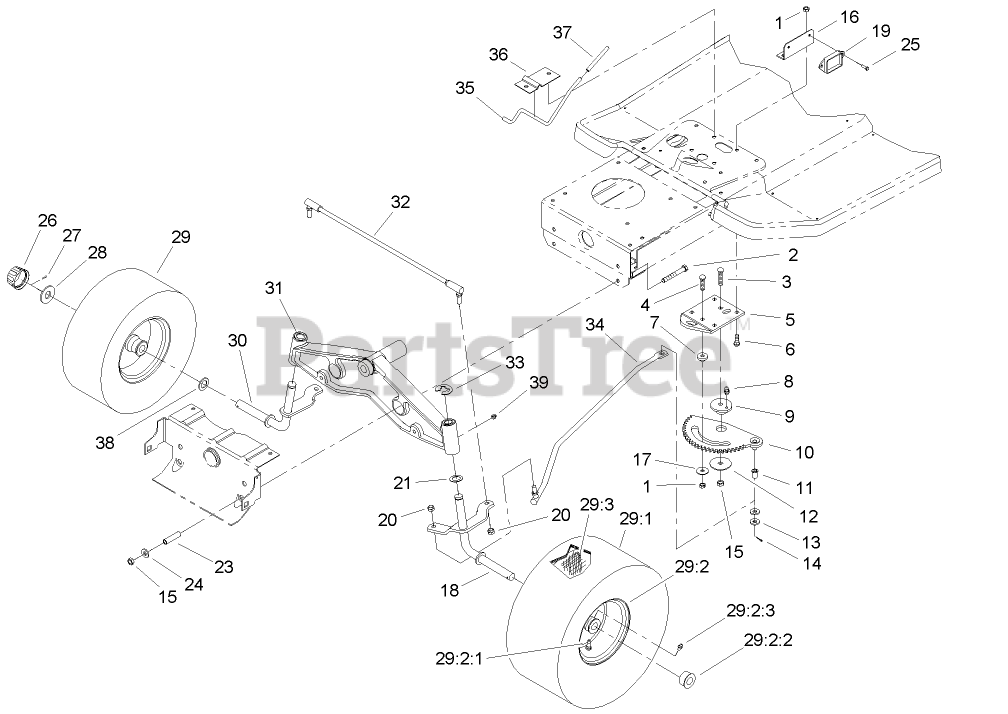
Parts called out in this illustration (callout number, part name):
1	NUT-LOCK, NI
2	SCREW-HH
3	SCREW-CARR
4	SCREW-CARR
5	BRACKET-RACK, STEERING
6	BOLT-CARR
7	SPACER-RACK, STEERING
8	FITTING-GREASE
9	BUSHING-ECCENTRIC
10	RACK-STEERING
11	BUSHING-FLANGED, NYLON
12	WASHER-BEARING
13	WASHER-FLAT
14	PIN-COTTER
15	NUT-LOCK, NI
16	BRACKET-MODULE
17	WASHER-PIVOT
18	LH SPINDLE ASM (BLACK)
19	MODULE
20	NUT-HEX
21	WASHER-THRUST
23	SPACER
24	WASHER-FLAT
25	SCREW-HWH
26	CAP-HUB
27	PIN-COTTER
28	WASHER-PLAIN
29	Loose Parts Package
29:2:2	BEARING-WHEEL
29:2:3	FITTING-GREASE
29:3	TUBE-INNER
30	RH SPINDLE ASM
31	AXLE-FRONT
32	TIE ROD ASM
33	E-RING
34	LINK-DRAG
35	ROD-BRAKE, PARKING
36	BRACKET-PARKING BRAKE
37	GRIP-BRAKE, PARKING
38	WASHER-THRUST
39	FITTING-GREASE
